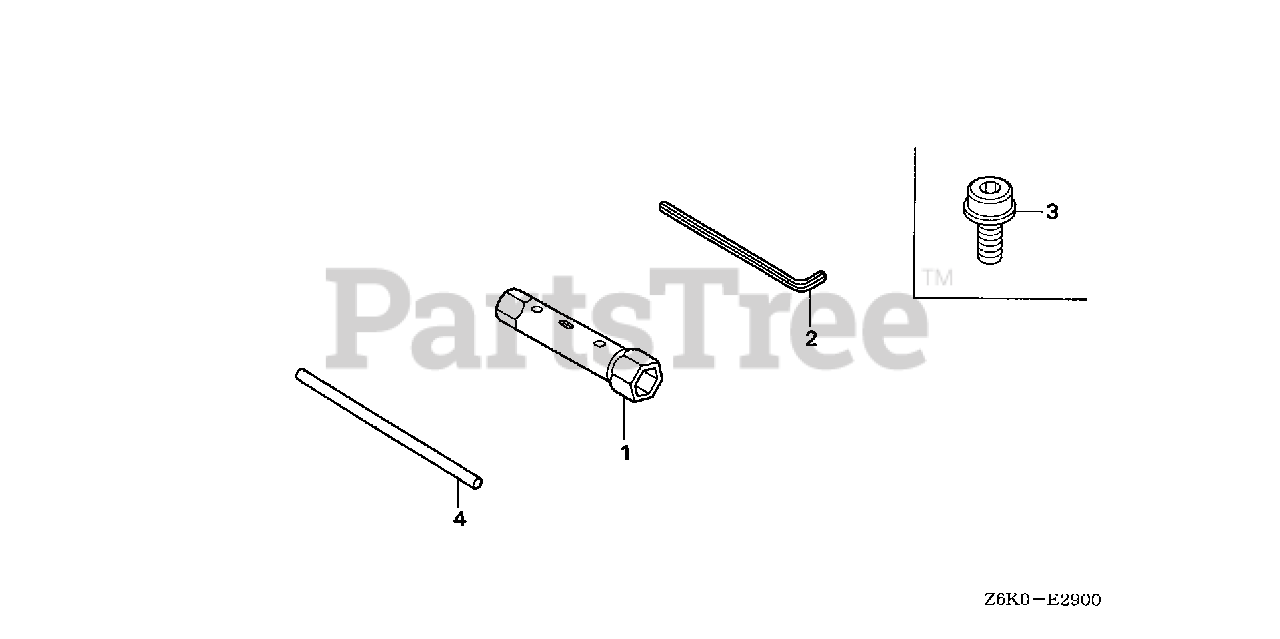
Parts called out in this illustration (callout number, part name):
1	WRENCH, PLUG (16X19)
2	WRENCH, HEX. (4MM)
3	BOLT, SOCKET (5X9)
4	BAR A, HANDLE
